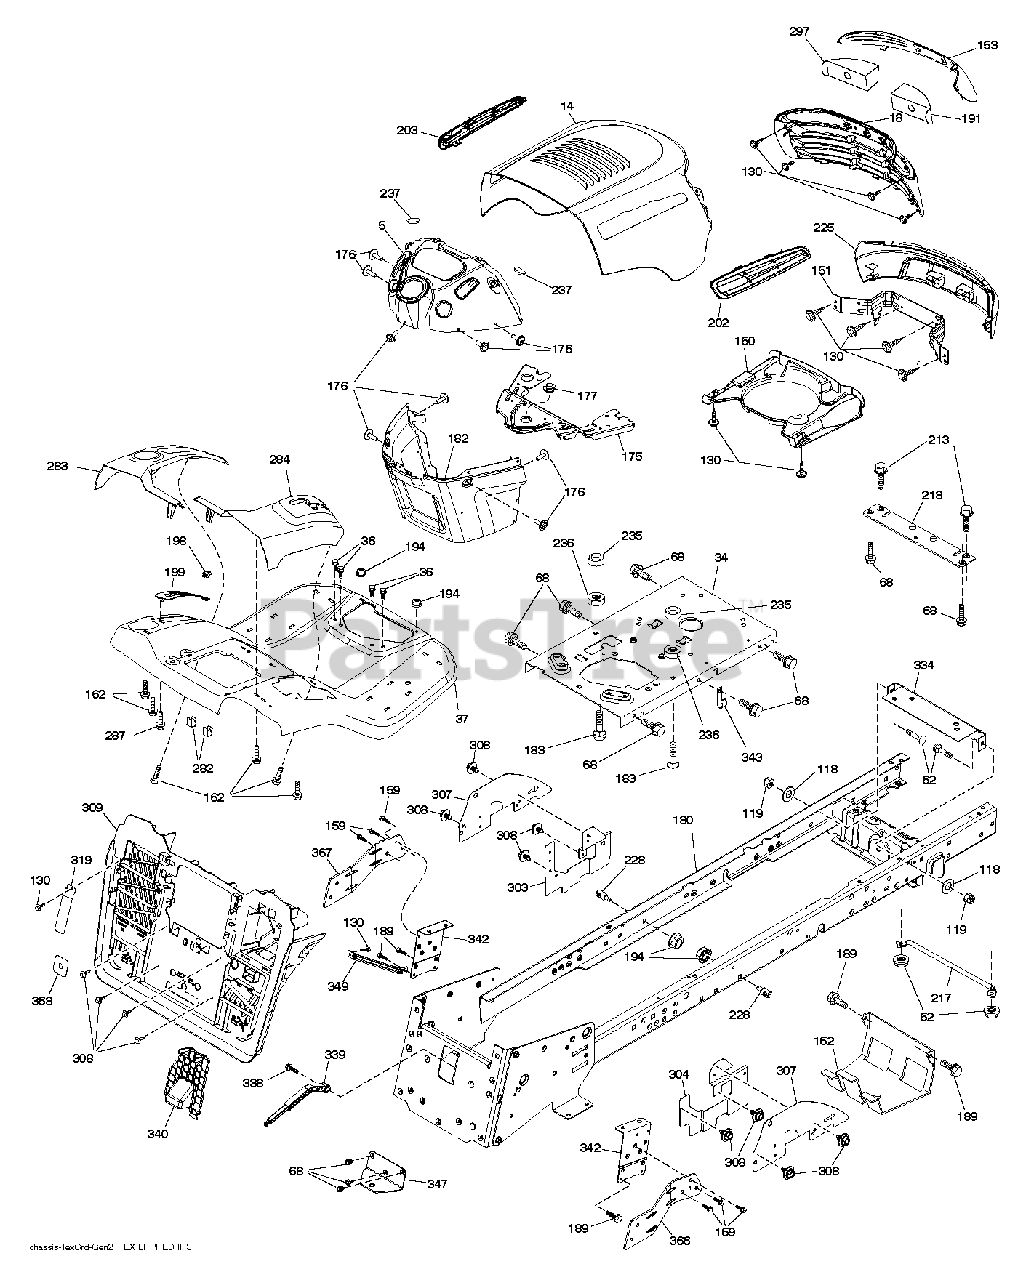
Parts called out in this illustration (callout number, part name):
36	SCREW 5/16"
52	LOCKNUT
119	LOCKNUT
130	SCREW.#10 X 0.750.BOS THREAD
151	BRACKET.PIVOT.ALPHA.LT
152	SHIELD BROWNING
153	LENS.PREDATOR.LT
159	SCREW, 3/8-16X3/4
162	SCREW.HI-LO.CONSOLE
175	CROSSMEMBER
176	SCREW.#10-24X5/8.RN.QU
177	BUSHING STEERING
180	WELDMENT.CHASSIS.TEX.
182	DASH.LWER.PREDATOR/HUSQ.LT
183	BOLT.5/16-18X1-1/4 FULL THD
189	SCREW
191	INSERT.REFLECT.PREDATOR.LT.RH
194	NUT LOCK HEX FLANGE 5/16-18
198	INDICATOR.DECK.LIFT.RED
213	BOLT
217	ROD.PIVOT.HOOD
218	X-PIECE.HOOD.STOP.NON/
228	STUD.FASTNER.W/ANTI-ROTATE
235	SPACER FENDER
236	NUT.CENTERLOCK.5/16-
237	PLUG.MOUNT.CARGO.BLK
282	CLIP.RETAINER.CONSOLE.LT.HUSQ
297	REFLECTOR.INSERT.PRED.LH.LT
304	SHIELD.LWR.RH.LT30DECK.PNT.BLK
308	BOLT, 5/16-18 X 1 3/4
309	BACKPLATE.ASM.CRDII.A
